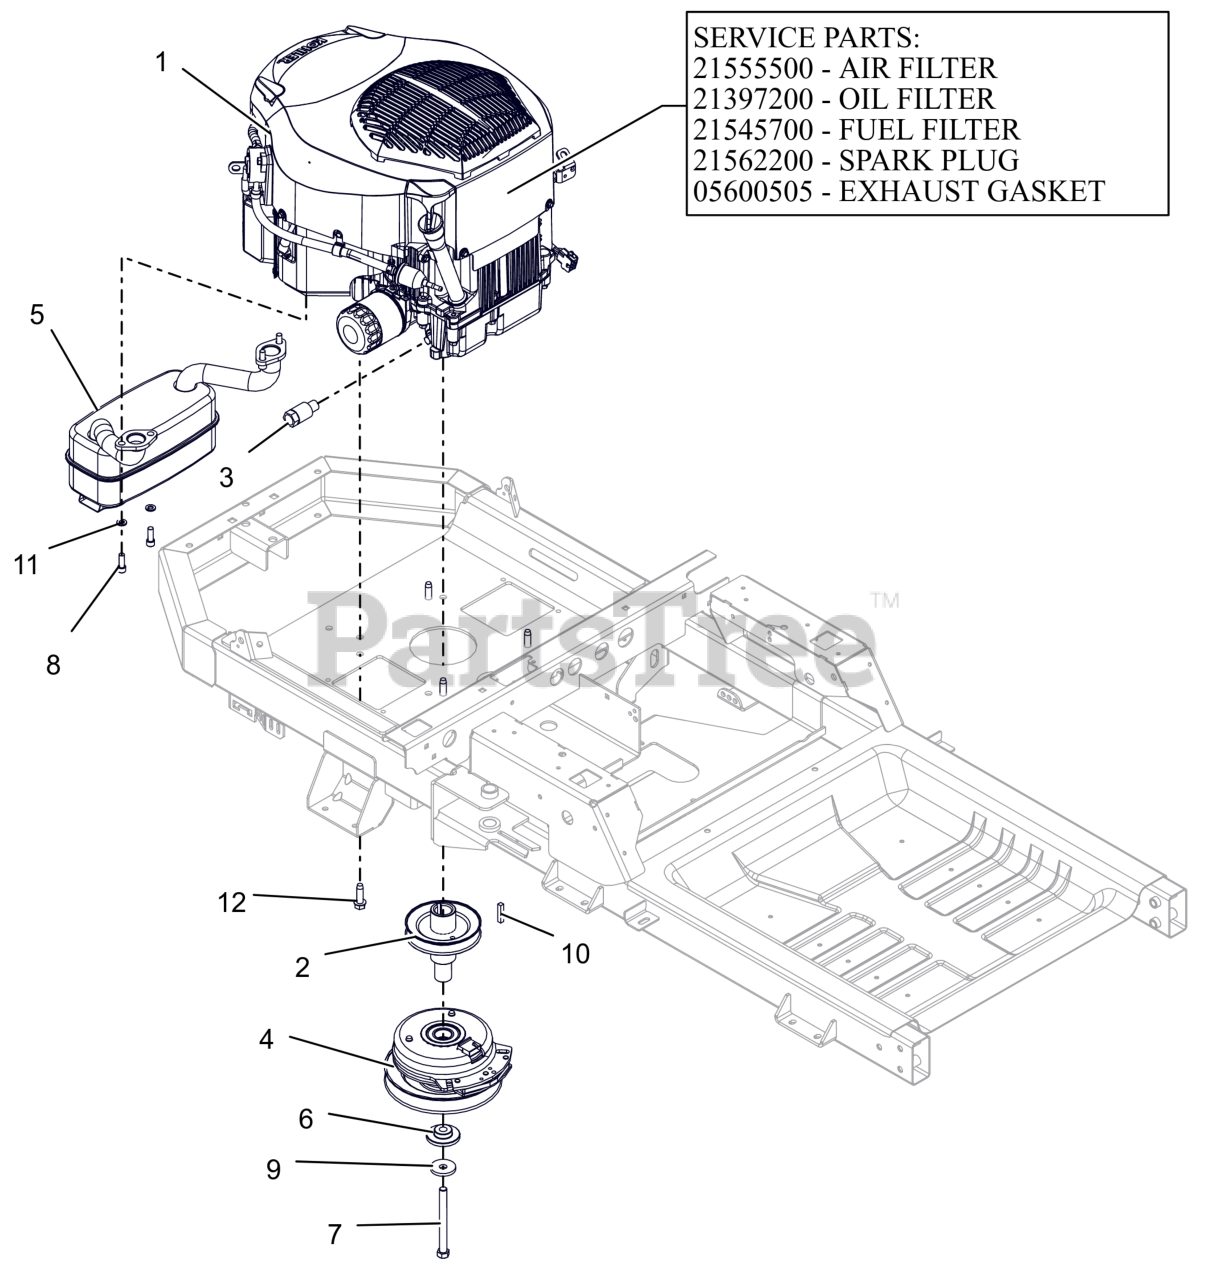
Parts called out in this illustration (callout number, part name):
1	ENGINE, KOHLER 24HP TWIN
1	AIR CLEANER, KOHLER
1	FILTER, OIL - KOH CV20
1	FILTER-FUEL KOHLER COURAGE PRO
1	PLUG, SPARK (RFI)
1	GASKET, MUFFLER COURAGE TWIN
2	WLDMT, DRIVE SHEAVE-X
3	DRAIN, OIL
4	CLUTCH,105FTLB MONOPOLE 6.83"
5	MUFFLER - KOHLER
6	BSHG-FLG .469X1.06X.574X2.0
7	BLT, HEX .44-20X4.50 G8 ZCC NT
8	SCR-CAP .31-18X.88 S/HD G8 ZCC
9	WASHER, 7/16" SPRING DISK
10	KEY-SQ .25 X 1.25 X .25 SAE
11	WSHR,LK-REG .312X.078 ZCC
12	SCR,TAP .375-16X1.25HWH TR ZCC
